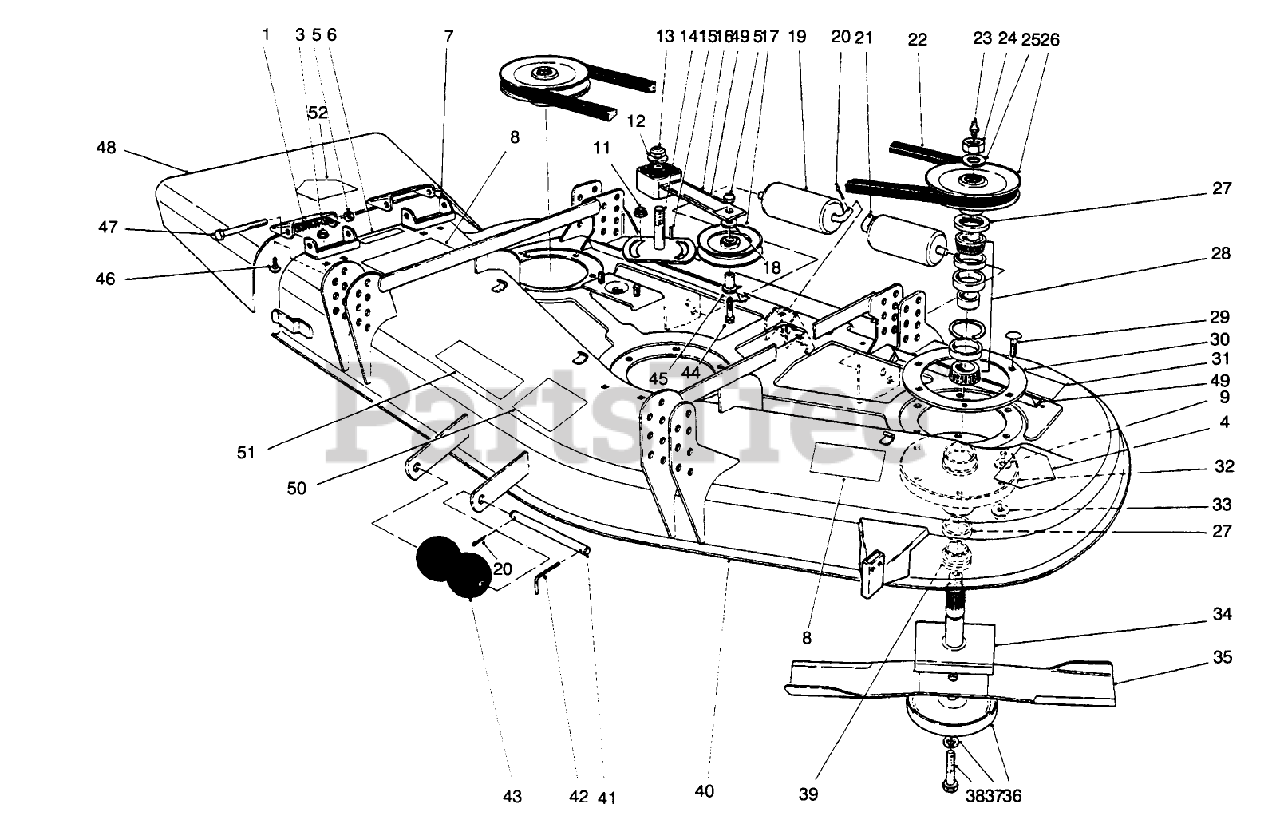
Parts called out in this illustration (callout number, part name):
1	SPRING
3	NUT-HF
4	DECAL-DANGER
5	NUT-HEX
6	DECAL-DANGER
7	Bracket-Pivot
8	DECAL-DANGER, THROWN OBJECT
9	WASHER-FLAT
11	NUT-HHF, WHIZ
12	WASHER-FLAT
13	NUT-LOCK, NI
14	PLATE-IDLER
15	KEY-SQUARE
16	IDLER ARM ASM
17	PULLEY-IDLER
18	WASHER-FLAT
19	ROLLER-DECK
20	PIN-COTTER
21	SHAFT-ROLLER, REAR
22	V-BELT
23	FITTING-GREASE
24	NUT-HEX
25	WASHER
26	PULLEY AND HUB ASM
27	SEAL-OIL
28	BEARING ASM
29	SCREW-CARR
30	SUPPORT-DECK, RING
31	DECAL-TORQUE
32	HOUSING-SPINDLE
33	NUT-HF
34	SHAFT
35	Blade
36	CUP-SCALP, ANTI
37	WASHER-LOCK
38	SCREW-BLADE
39	SPACER
40	Cutting Deck
41	SHAFT-ROLLER
42	PIN-SPECIAL
43	ROLLER
44	SCREW-HH
45	BUSHING-PULLEY
46	SCREW-CARR
47	SCREW-HH
48	Deflector-Grass (Incl. Ref. #52)
49	DECAL-DANGER
50	DECAL
51	DECAL-PROLINE
52	DECAL-DANGER
